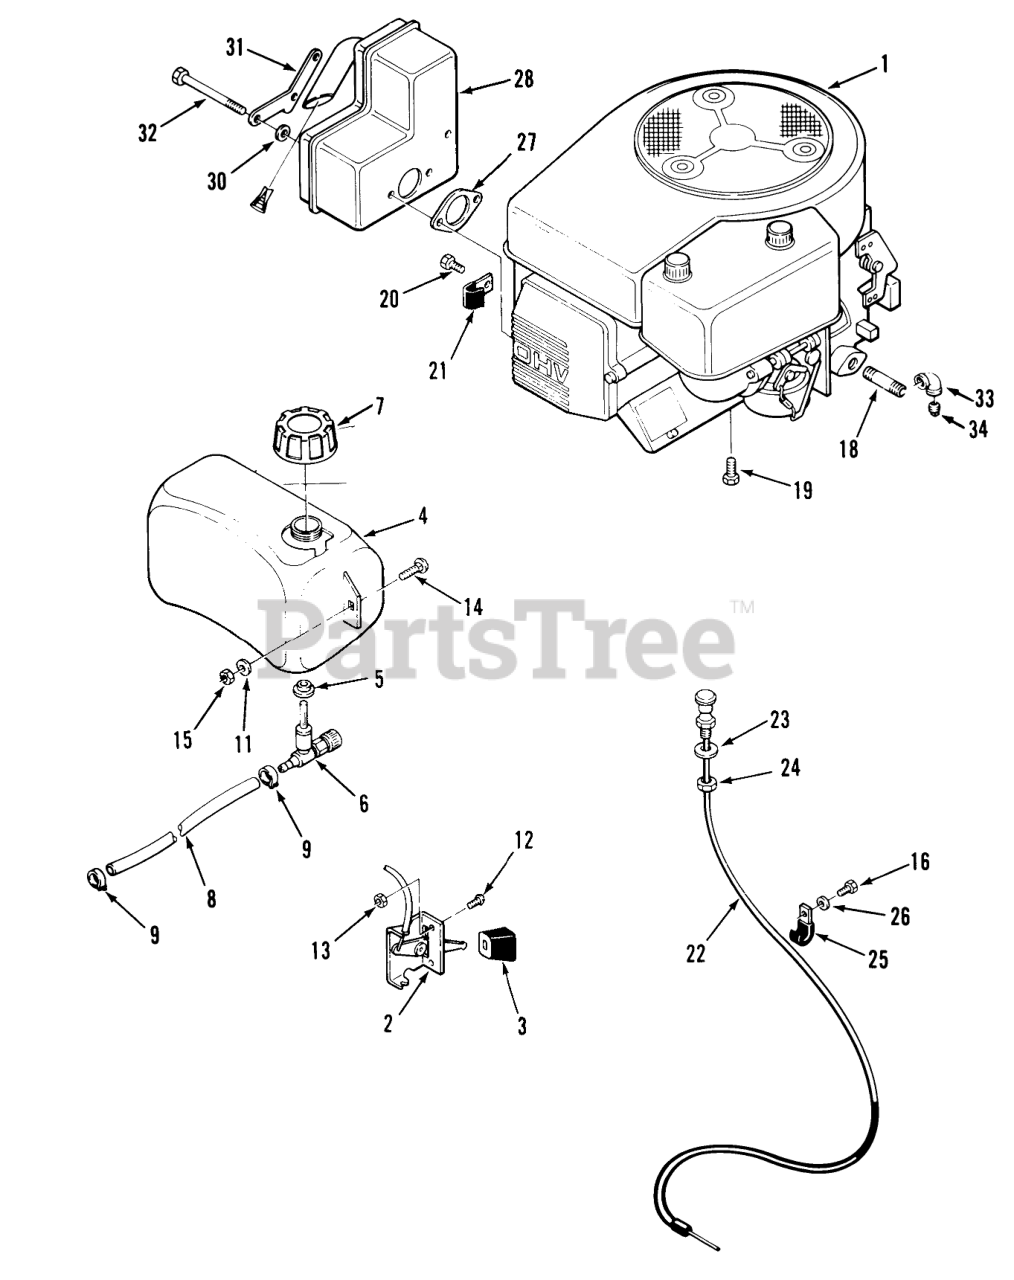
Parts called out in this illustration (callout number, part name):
1	Engine-12HP-Toro Power Plus Model E125V-N/11102B
2	THROTTLE-CONTROL
3	KNOB-CONTROL
4	Fuel Tank
5	BUSHING
6	VALVE-FUEL
7	GAS CAP ASM
8	Fuel Line 25.5"
9	Clamp
11	WASHER 5/16 SAE
12	Screw
13	Nut
14	Carriage Bolt 5/16-18 x 3/4
15	Nut
16	Bolt
18	NIPPLE-PIPE (3.5 IN)
19	Bolt
20	HHCS M8X1.25X15
21	J-CLIP
22	CONTROL-CHOKE
23	Washer
24	NUT-HEX PALNUT
25	CLIP
26	Washer
27	GASKET-EXHAUST
28	MUFFLER
30	Nut-M8
31	Bolt Retainer
32	HHCS-M8 X 100MM
33	Plug
34	ELBOW 3/8 90 DEG
